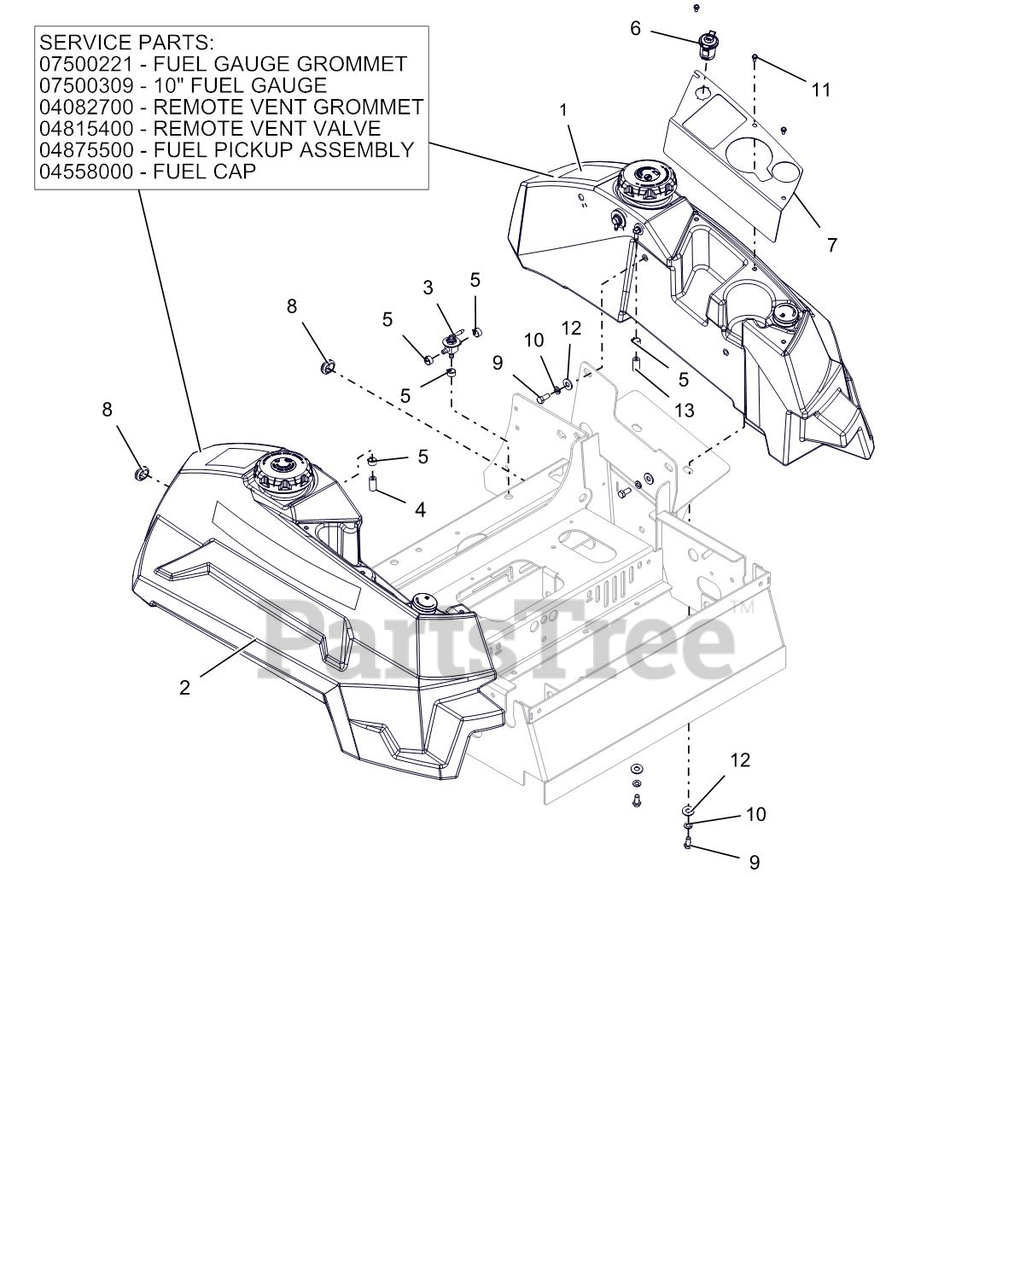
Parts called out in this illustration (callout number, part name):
1	ASM, LH FUEL TANK
2	ASSY-RH, PT400 FUEL TANK
3	VALVE - FUEL
4	HOSE, .25 LOW-PERM BULK GAS
5	CLAMP, FUEL LINE
6	PORT, 12 VOLT POWER
7	CUP HOLDER/POCKET PLATE - RED
8	GROMMET,RUBBER 5/8 ID/1.13 OD
9	@BLT-HEX .31-18X.75 GR5 YWZC
10	@WSHR-LK .31X.078 REG YWZC
11	SCR-MCH 10-24X.38 HWHSTAINLESS
12	@WSHR-FL-STL.38X.875X.083 YWZC
13	HOSE, .25 LOW-PERM BULK GAS
14	GROMMET, FUEL GAUGE
15	GAUGE, REMOTE FUEL SEALED 10"
16	GROMMET, REMOTE VENT NITRILE
17	VALVE, 2-WAY
18	ASSM,LRG TANK FUEL PICKUP LINE
19	CAP, FUEL VENTIN AUTOLOCK
